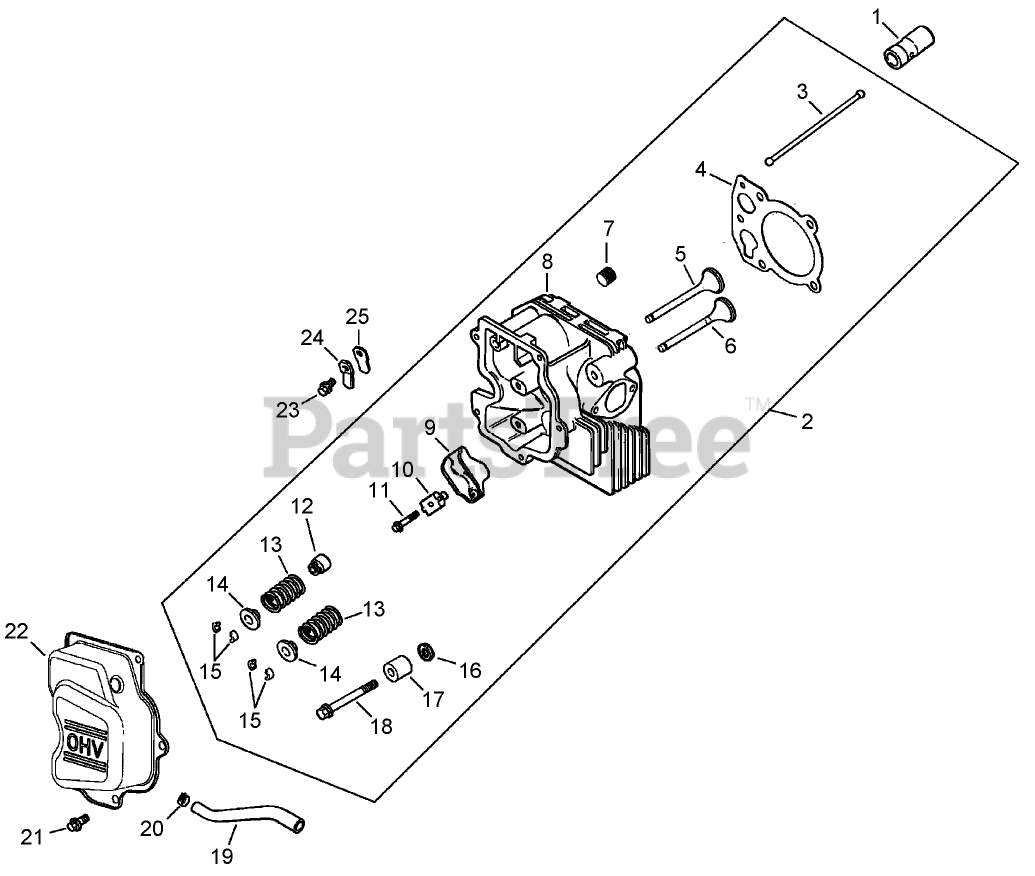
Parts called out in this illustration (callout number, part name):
1	Lifter-Valve
2	Cylinder Head Kit (Includes 3-18, carburetor gasket 12 041 01-S (2), air cleaner base gasket 12 041 02-S, & exhaust manifold gasket 12 041 03-S)
3	Rod-Push
4	Gasket-Head, Cylinder
5	Valve-Intake (STD)
6	Valve-Exhaust (STD)
7	PLUG-PIPE, COUNTERSUNK (1/8)
8	Head-Cylinder
9	ARM-ROCKER
10	Pivot-Arm, Rocker
11	SCREW-FLANGE (M6X1.0X34)
12	SEAL-STEM, VALVE
13	Spring-Valve
14	CAP-SPRING, VALVE
15	RETAINER KIT
16	Washer-Flat (1/2)
17	Spacer-Head Bolt (Exhaust Port)
18	Screw-Flange, Hex (M10x1.5x37)
19	Hose-Breather
20	CLAMP-HOSE, SPRING (1/2)
21	SCREW-FLANGE, THREAD FORMING (M6X1.0X16)
22	Cover-Valve
23	SCREW-HHFTF (M5X.80X10)
24	RETAINER-REED
25	REED-BREATHER
